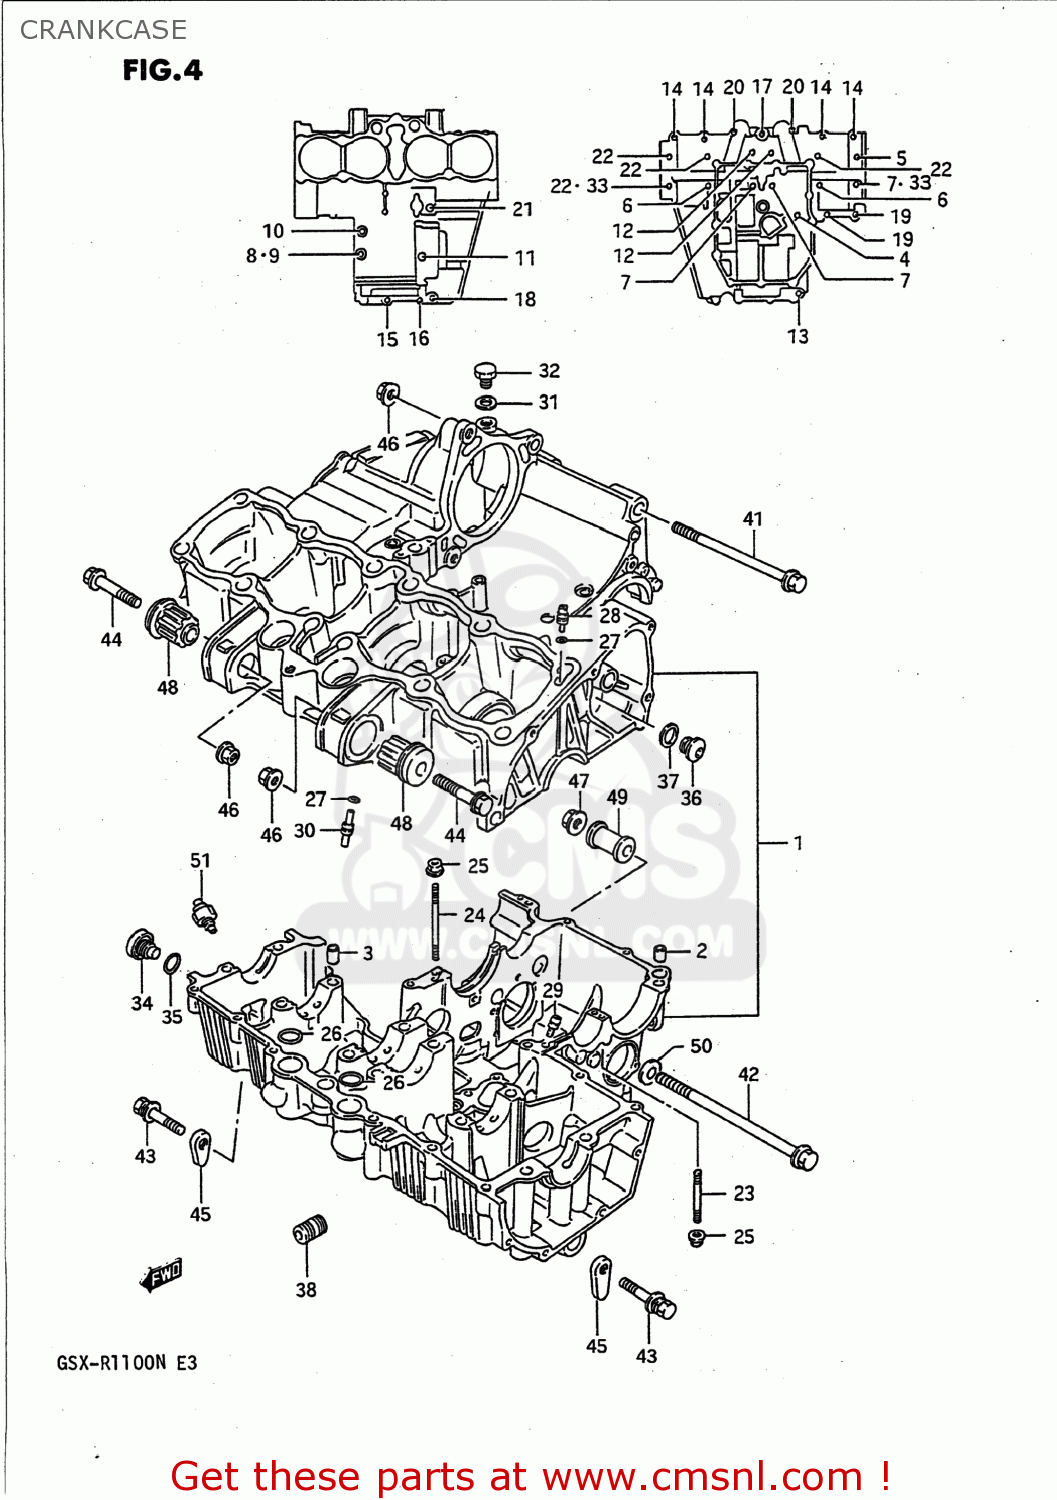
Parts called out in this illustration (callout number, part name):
1	CRANKCASE SET
2	PIN(10.4X13X22)
3	PIN (11X20)(SUS)
4	BOLT(6X105)
5	BOLT(8X105)
6	BOLT(8X125)
7	BOLT(8X115)
8	BOLT 6X55
9	GASKET(6.2X13X1.2) (NAS)
10	BOLT
11	BOLT
12	BOLT
13	BOLT 8X60
14	BOLT 6X35
15	BOLT
16	BOLT
17	BOLT 6X50
18	BOLT ,6X60
19	BOLT
20	BOLT
21	BOLT
22	BOLT(8X95)
23	STUD BOLT
24	STUD BOLT
25	NUT
26	O RING(D:2.5,ID:21)
27	O RING(D:1.2,ID:4)
28	JET,AIR
29	JET
30	JET,OIL GALLERY
31	GASKET(12.1X16.2X3.7) (NAS)
32	PLUG(12X9)
33	GASKET(8.5X17X2.3) (NAS)
34	PLUG
35	O RING(D:2.4,ID:16.8)
36	PLUG,14X12
37	GASKET(14X19.2X2) (NAS)
38	UNION,OIL STAND
39	BEARING,CRANK THRUST(GREEN)
40	BEARING,CRANK THRUST(RED)
41	BOLT 10X150
42	BOLT(12X178)
43	BOLT 10X60
44	BOLT 10X55
45	NUT
46	NUT
47	NUT 12MM
48	BUSH,ENGINE MOUNTING
49	SPACER,ENGINE MOUNTING
50	WASHER
51	SWITCH ASSEMBLY
